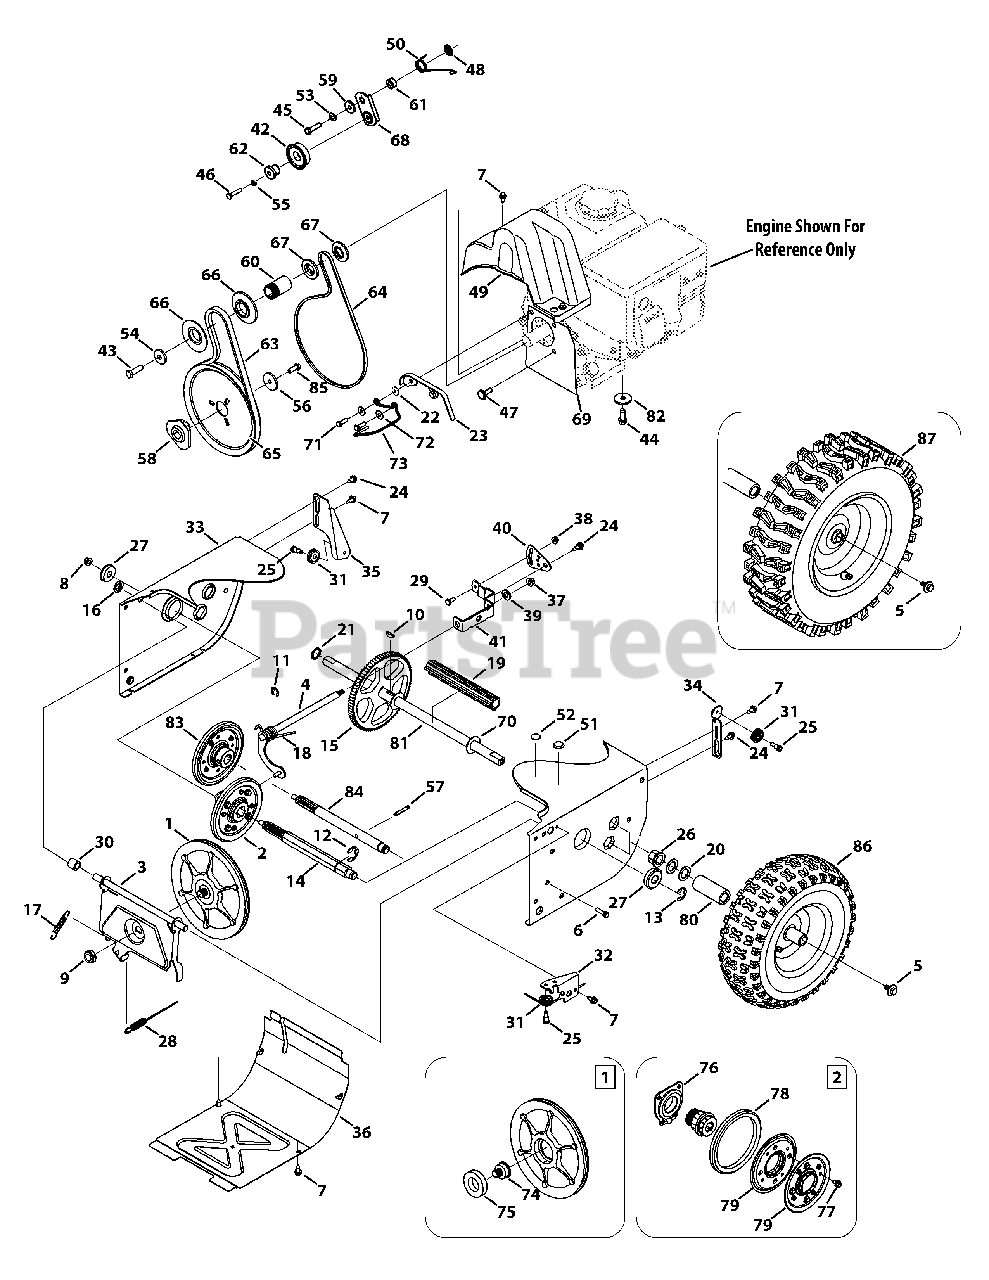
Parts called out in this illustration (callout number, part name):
1	Disc Assembly, Friction Wheel
2	Friction Wheel Assembly, 5.5 OD
3	Friction Wheel Support Bracket
4	Rod Shift Assembly
5	Screw, 5/16-24 x .750
6	Taptite Screw, 1/4-20 x 1.000
7	Taptite Screw, 1/4-20 x .625
8	Flange Lock Nut, 3/8-16
9	Flange Nut, 5/8-18
10	Hi-pro Key, 3/16 x 3/4 Dia.
11	E-Ring
12	Retaining E-Ring, .875 Dia.
13	E-Ring, .750 Dia.
14	Hex Shaft, 7-Tooth
15	Gear, 80-Tooth
16	Speed Nut, .500
17	Extension Spring
18	Torsion Spring, .750 x .968
19	Axle Spacer
20	Flat Washer, .793 x 1.24 x .060
21	Flat Washer, .75 x 1.00 x .060
22	Washer, Flat, .330 x .687 x .030
23	Belt Cover
24	Shoulder Screw, .368 x .113, 1/4-20
25	Shoulder Screw, 1/4-28, .340 x .355
26	Hex Flange Bearing
27	Ball Bearing, 17 x 40 x 12
28	Wheel Clutch Cable, 44.955"
29	Hex Head Screw, 1/4-20 x .620
30	Spacer, .508 ID x .75 OD x .68
31	Cable Roller
32	Auger Cable Front Guide Bracket
33	Frame
34	Auger Cable Guide Bracket
35	Drive Cable Guide Bracket
36	Frame Cover
37	Flange Lock Nut, 5/16-18
38	Flange Lock Nut, 1/4-20
39	Washer, Flat, .469 x .875 x .105
40	Speed Selector Pivot Bracket
41	Speed Selector Shift Bracket
42	Idler Pulley Assembly
43	Hex Screw, 3/8-24 x 1.25
44	Sems Screw, 3/8-16 x 1.00
45	Hex Screw, 5/16-24 x 1.25
46	Hex Screw, 1/4-20 x 1.25
47	Shoulder Screw, 5/16-24 x .5
48	Push-on Nut, .25 Dia.
49	Belt Cover, 4-Way
50	Torsion Spring, .850 ID x .333
51	Plug, 3/8 ID
52	Plug, 1/2 ID
53	Lock Washer, 5/16
54	Flat Washer, .45 x 1.5 x .172
55	Washer, Lock, 1/4
56	Flat Washer, .34 x 1.50 x .150
57	Pin, Spirol, 2.5"
58	Adapter Pulley, .75 Dia.
59	Shoulder Spacer, .3175 x .5 x .0975
60	Spacer, .875 ID x 1.185 OD
61	Spacer, .340 x .750 x .330
62	Shoulder Space, .260 x .785 x .538
63	Auger Drive Belt, Standard
64	Wheel Drive Belt, Standard
65	Auger Drive Pulley, 8.1 x .5
66	Pulley Half, 2.600 OD
67	Pulley Half, 3/8 x 1.716 OD
68	Wheel Drive Idler Bracket
69	Cover Plate, Standard
70	Washer, Flat, .760 x 1.49 x .060
71	Hex Head Screw, 5/16-24 x 1.00
72	Washer, Flat, .349 x .879
73	Belt Guide
74	Friction Disc Bearing Pin
75	Ball Bearing, 30 x 55 x 13
76	Bearing Assembly
77	Taptite Screw, 5/16-18 x .750
78	Friction Wheel Rubber
79	Friction Wheel Plate
80	Spacer, 1.25 x .75 x 3.0
81	Axle, .75 x 22
82	Washer, Flat, .38 x 1.38 x .125
83	Friction Wheel Ass’y, Single-Speed
84	Shaft, Single-Speed
85	Hex Cap Screw, 5/16-24 x .875
86	Snow Hog Wheel, 13 x 4 x 6
87	X-Trac Wheel, 15 x 5 x 6, LH
87	X-Trac Wheel, 15 x 5 x 6, RH
